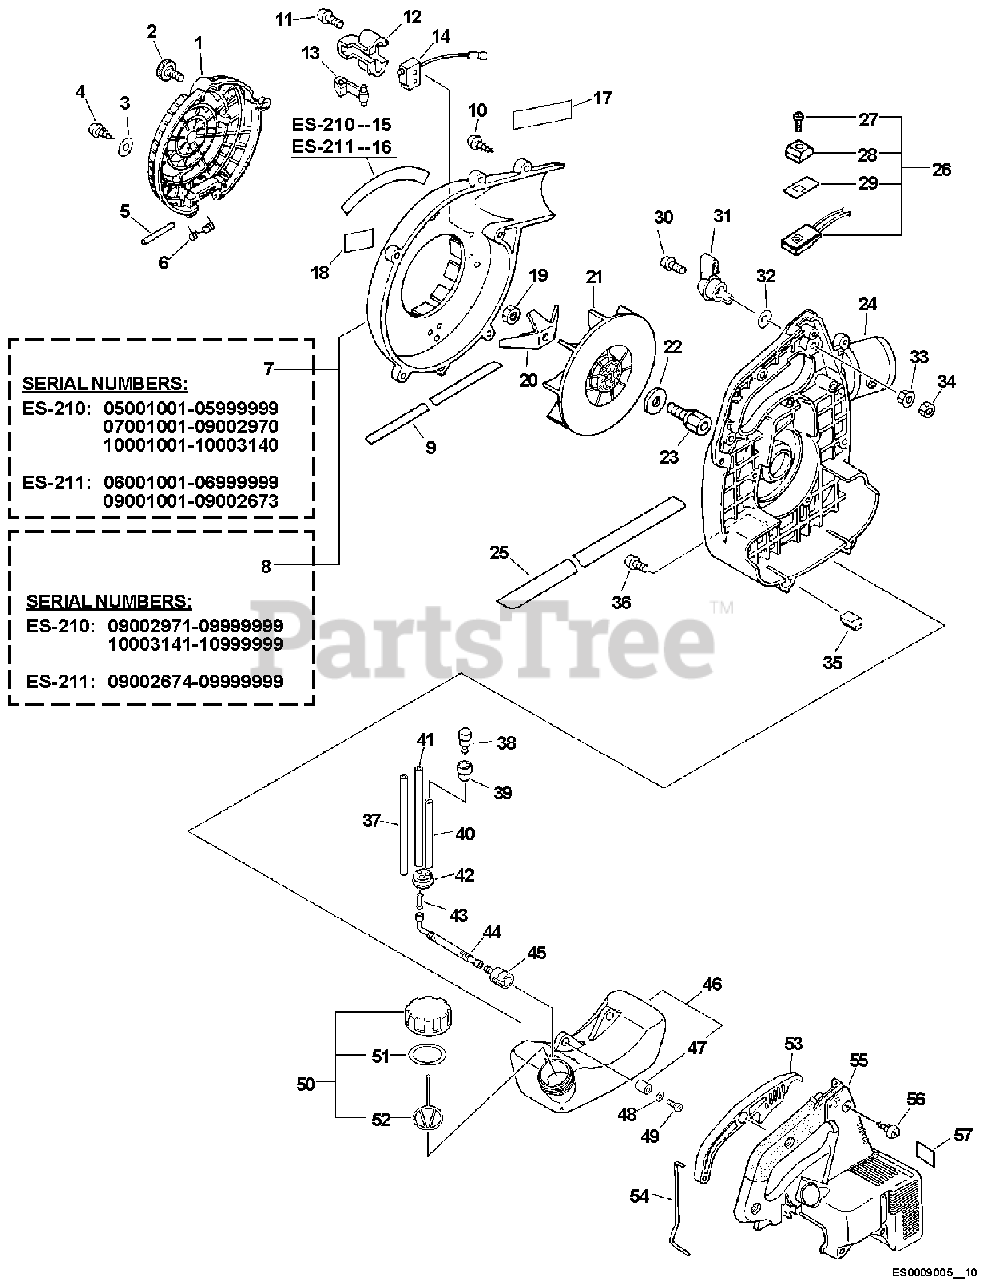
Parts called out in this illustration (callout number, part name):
1	COVER, INTAKE
2	THUMBSCREW
3	WASHER 5.5×12×0.8
4	SCREW 5×14
5	PIN, INTAKE COVER
6	SPRING, COIL
7	COVER, FAN - LEFT -- GRAY
8	COVER, FAN - LEFT -- GRAY
9	CUSHION
10	SCREW, TAPPING 5×20
11	SCREW 4×22
12	BRACKET, SWITCH
13	LEVER, SHUT OFF ACTUATOR
14	SWITCH, INTERLOCK
15	LABEL - MODEL ES-210
16	LABEL, MODEL
17	LABEL, CAUTION - ISO
18	LABEL, NOISE - 71DB(A) CAT. III
20	SHREDDER
23	HUB, FAN
24	FAN COVER ASSY - RIGHT -- GRAY
25	CUSHION
26	CABLE ASSY, CONTROL
27	SCREW 3×10
28	KNOB, SWITCH - ORANGE
29	LABEL, SWITCH
30	SCREW 5×25
31	CONTROL, THROTTLE
32	WASHER 5.5×12×0.8
33	NUT, FLANGE M5
36	SCREW 4×22
37	PIPE, FUEL RETURN 3×6×90 MM CLEAR
38	VENT ASSY
39	HOLDER, VENT
40	PIPE, FUEL 3x-5x-70 BLACK
41	PIPE, FUEL 3×5×90 BLACK
42	GROMMET, FUEL
43	CONNECTOR, PIPE
44	PIPE, FUEL 3×7×100 FLEXIBLE
45	FILTER, FUEL
46	TANK ASSY, FUEL
47	SPACER 6.2×7.8×6
48	WASHER 5.5×12×0.8
49	SCREW 5×16
50	CAP ASSY, FUEL
51	GASKET, FUEL CAP
52	CONNECTOR, CAP L= 100 MM
53	CONTROL, THROTTLE
54	ROD, THROTTLE
55	COVER, ENGINE
56	SCREW, TAPPING 5×20
57	LABEL, CAUTION - HOT
